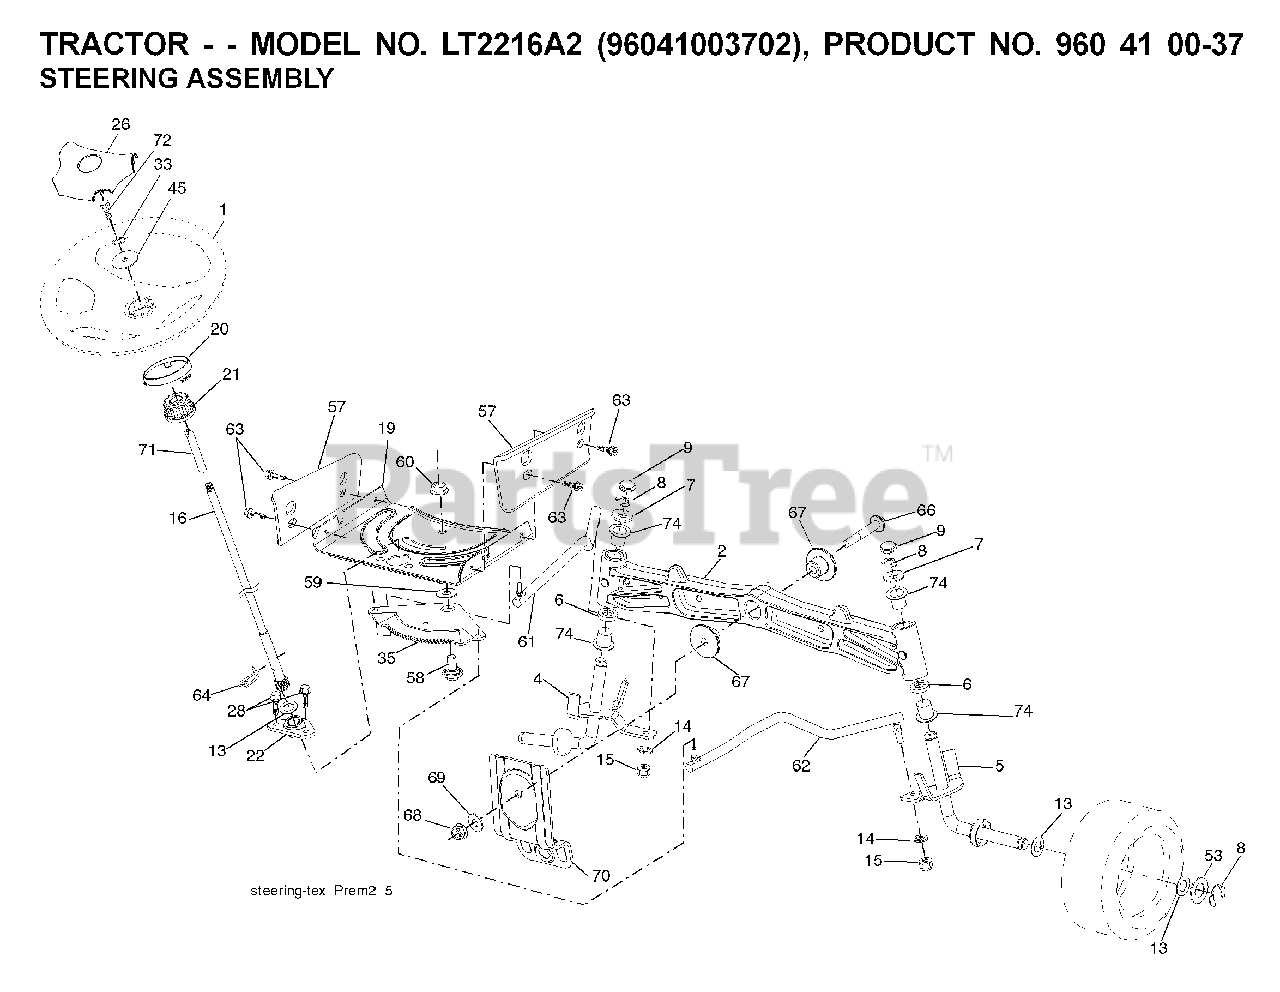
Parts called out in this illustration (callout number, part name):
2	AXLE.HALF.ASM.WELDED
4	SPINDLE.WELDED.LH.15"TEX
5	SPINDLE.WELDED.RH.15"T
8	RING CLIP
9	CAP.SPINDLE
14	WASHER, LOCK 3/8
15	NUT CROWNLOCK 3/8-24
16	SHAFT STEERING
19	PLATE.STEER.DDL.NLT/NG
20	BOOT STEERING BLACK
21	ADAPTER, WHEEL STNG..
22	BUSHING.ASM.STEERING.A
26	INSERT.CAP.STRG.WH.BLACK
28	SCREW, 3/8-16X3/4
33	LOCKWASHER
35	GEAR.SECTOR.PLATE.DDL.
45	WASHER.11/32
53	WASHER.HARDENED
57	BRACKET.UPSTOP.TEX
58	BOLT.SHOULDER.SECTOR.P
59	WASHER.THURST.SECTOR.S
60	NUT FLANGE LOCK 5/8-11
61	DRAGLINK.LH.BALLSTUD.D
62	DRAGLINK.RH.BALLSTUD.D
63	SCREW
64	RETAINER.CLIP.SPRING.S
66	BOLT HEX FGHD 7/16-14 X 3 SERR
67	BUSHING.PM.FRONT AXLE
68	NUT.LOCK.FLANGE.7/16
70	BRKT.DECK.SUSPENSION.F
71	SHAFT EXTENSION STEERING
72	BOLT YT
73	WASHER.1.5X.505X.118
74	BRNG T
